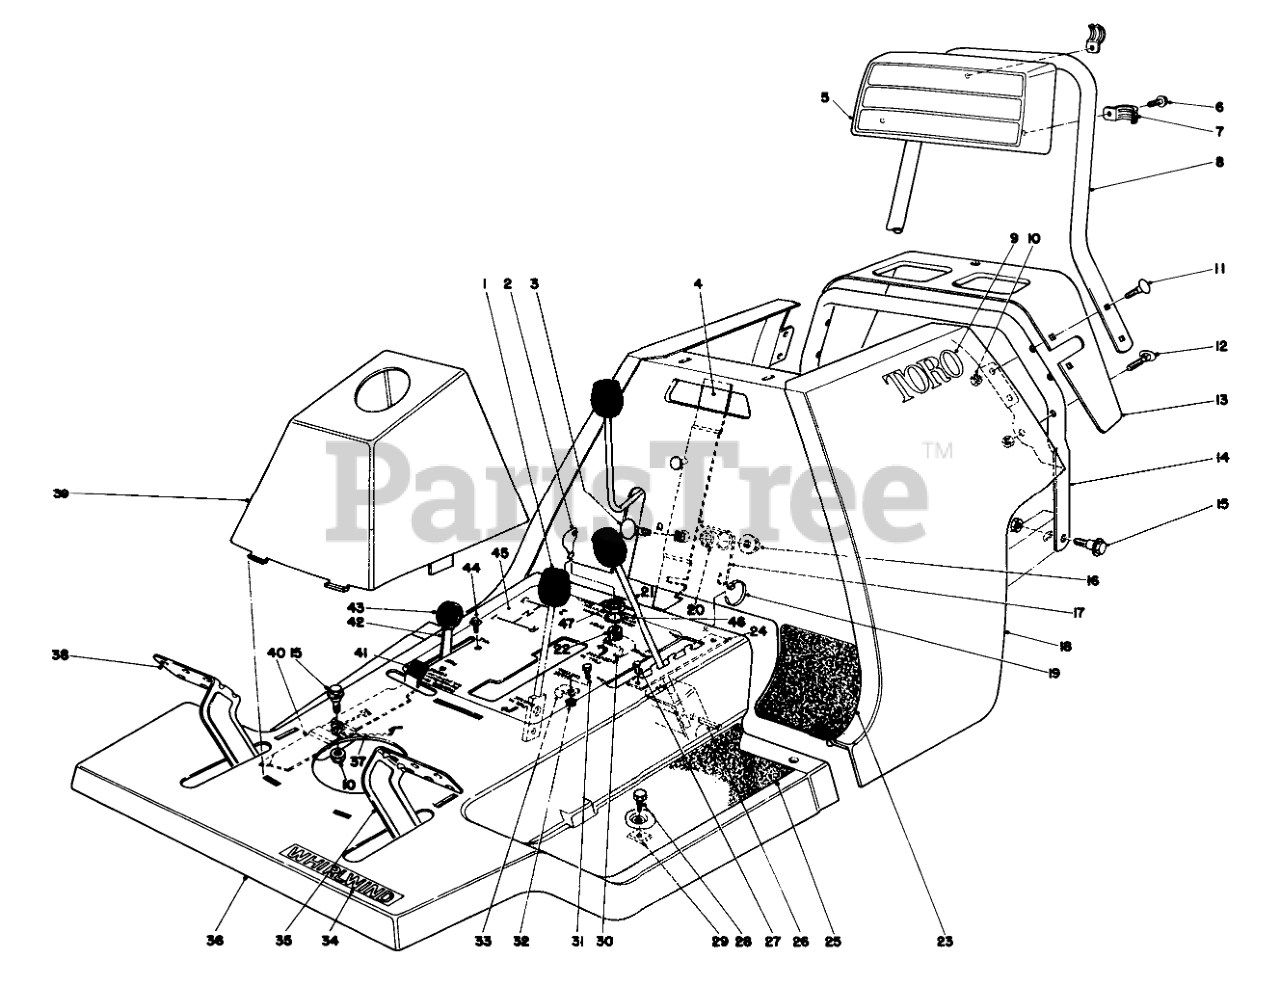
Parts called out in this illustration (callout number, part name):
2	Key
3	BOLT-CARR
4	Handle Latch
5	Backrest
6	SCREW-HHF
7	Clamp Conduit
8	Handle Upper
9	TORO LOGO DECAL
10	NUT-LOCK, CONE
11	SCREW-CARR
12	HANDLE SCREW
13	Extension Rear Body
14	Handle Lower
15	SCREW-SHOULDER
16	NUT-HF
17	Latch Return Spring
18	Rear Body
19	TIE-CABLE
20	Spacer
21	Height of Cut Lever
22	Starter Switch (Incl. Ref. #2, 46, 47)
23	Heel Pad-LH.
24	Height Adjustment Plate
25	Foot Tread LH.
26	PIN-SPECIAL
28	SCREW-HH
29	NUT-TINNERMAN
32	NUT-KEPS
33	CABLE CLAMP
34	WW DECAL
35	Clutch Pedal
36	Body-Front (Incl. Ref. #24, 27 & 45)
37	SPRING-PARKING BRAKE
38	Brake Pedal
39	Tower
40	Parking Brake
41	TIP-PARKING BRAKE
42	Throttle Control (Incl. Ref. #43)
44	8X1/2 SELF TAP SCREW
45	Decal-Front Body
46	WASHER-TOOTH, INTERNAL
47	NUT-HH
